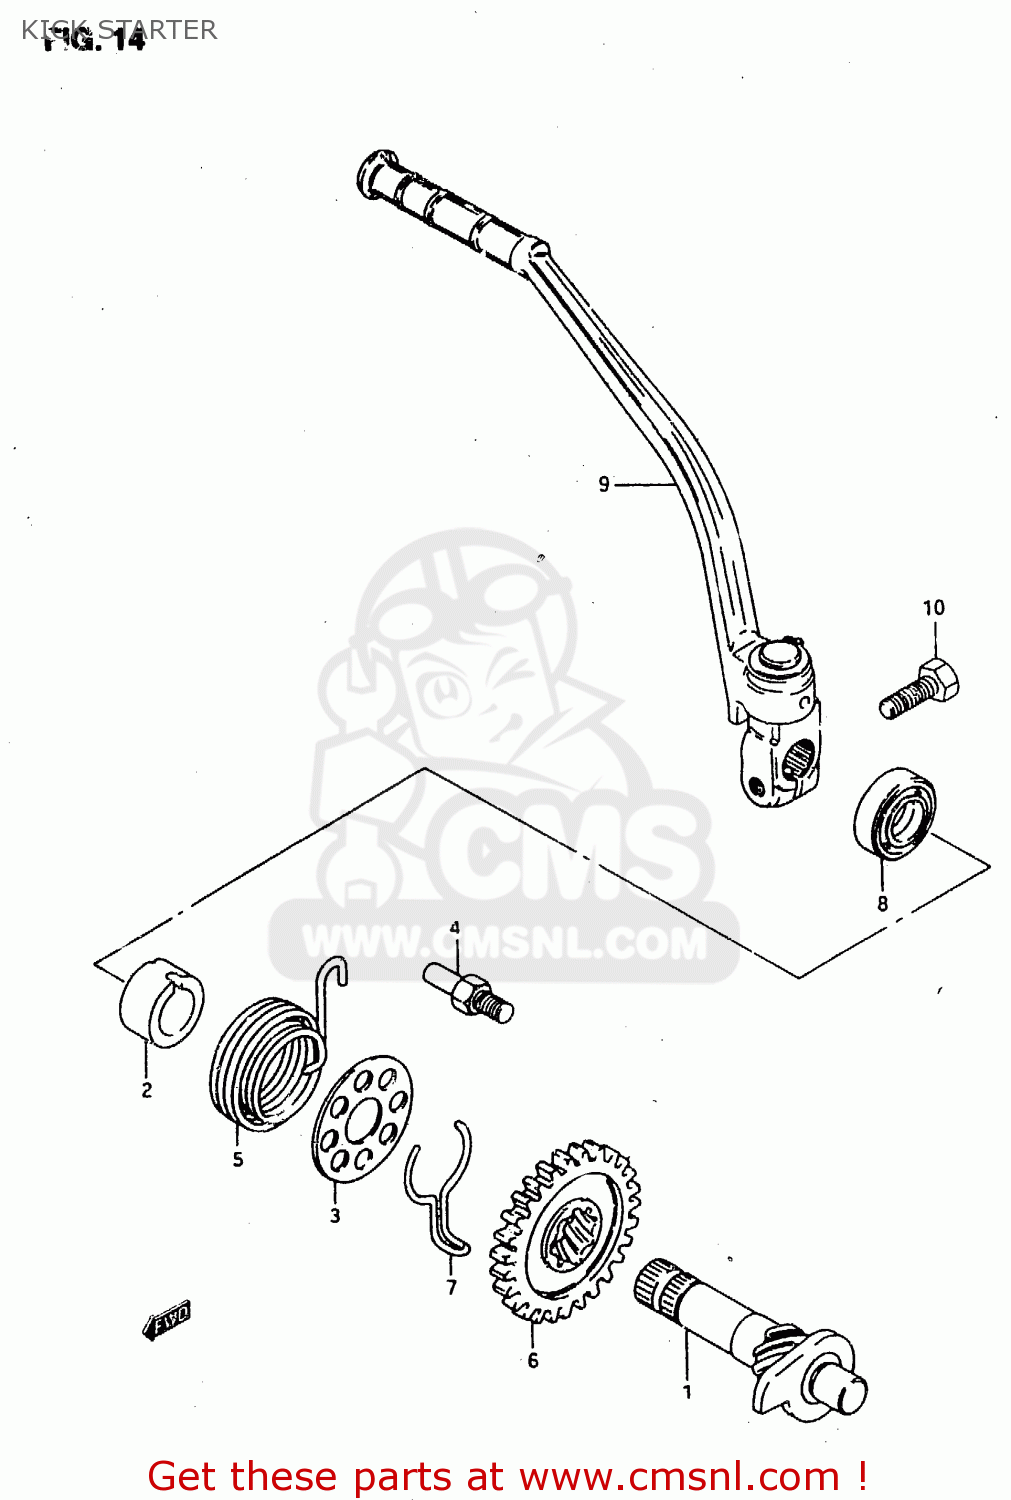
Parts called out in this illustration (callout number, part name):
1	SHAFT,KICK STARTER
2	GUIDE,KICK STARTER SFT SPRING
3	HOLDER,KICK STARTER SHAFT SPR
4	BOLT,KICK START SHAFT SPR HOOK
5	SPRING
6	GEAR, KICK STARTER DRV.
7	SPRING,KICK STARTER RETAINER
8	SEAL,OIL(14X24X6)
9	LEVER ASSY, KICK STARTER
10	BOLT
